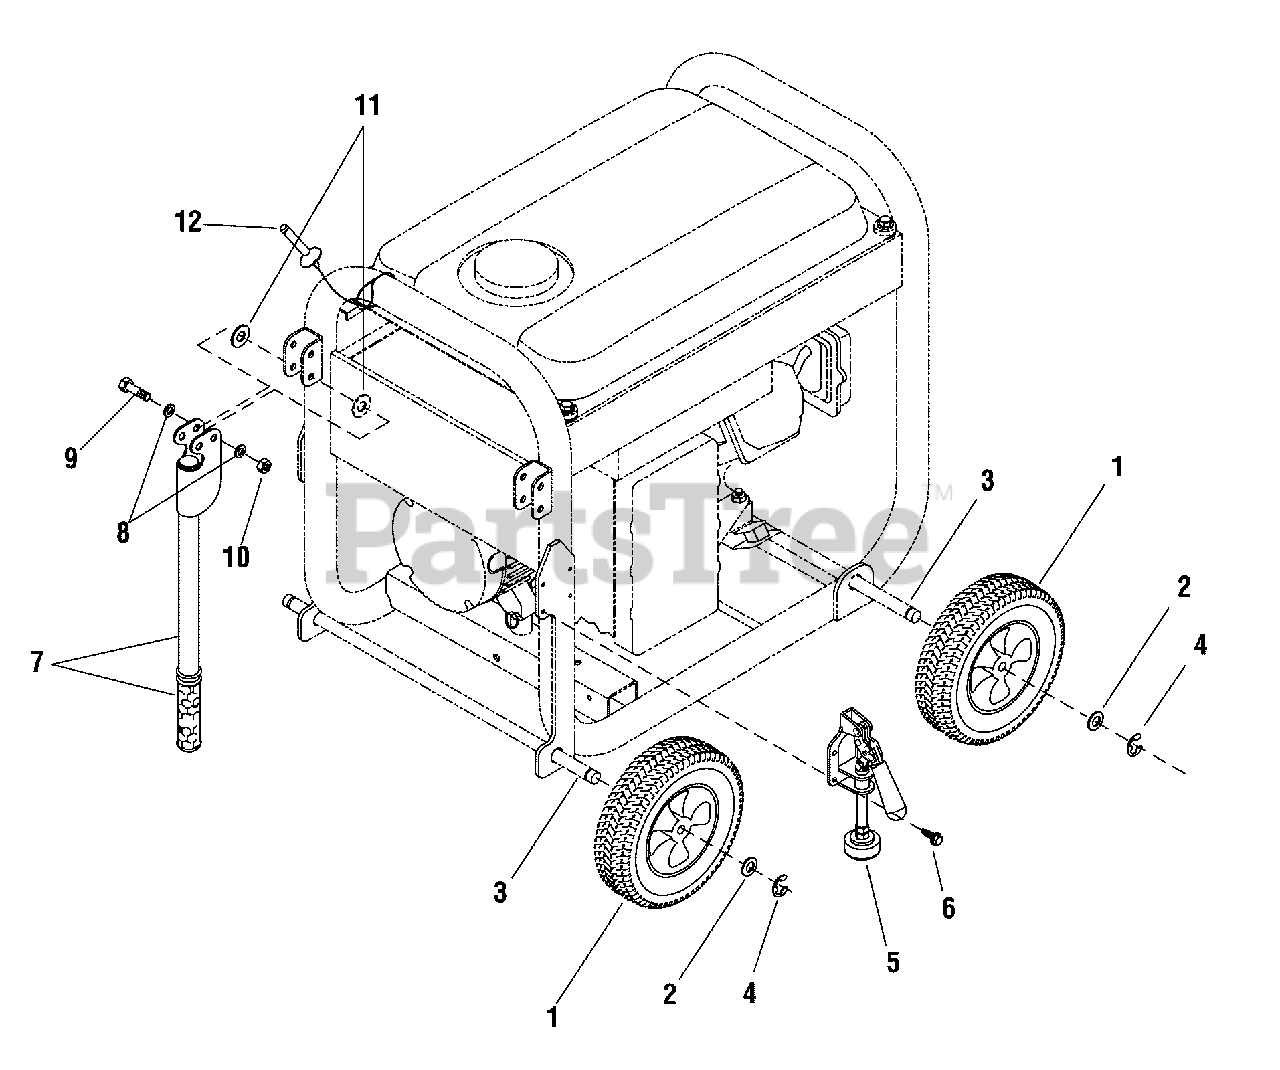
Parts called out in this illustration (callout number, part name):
2	* WASHER-5/8
4	E-RING
6	* SCREW-1/4-20 x 3/8
8	* WASHER-FLAT 5/16 - M8
9	* NUT- M8 - 1.25, NYLOK
10	* CAPSCREW, HEX HEAD, M8 - 1.25 x 45
11	* WASHER-1.2 x 0.346 x 0.03, NYLON
